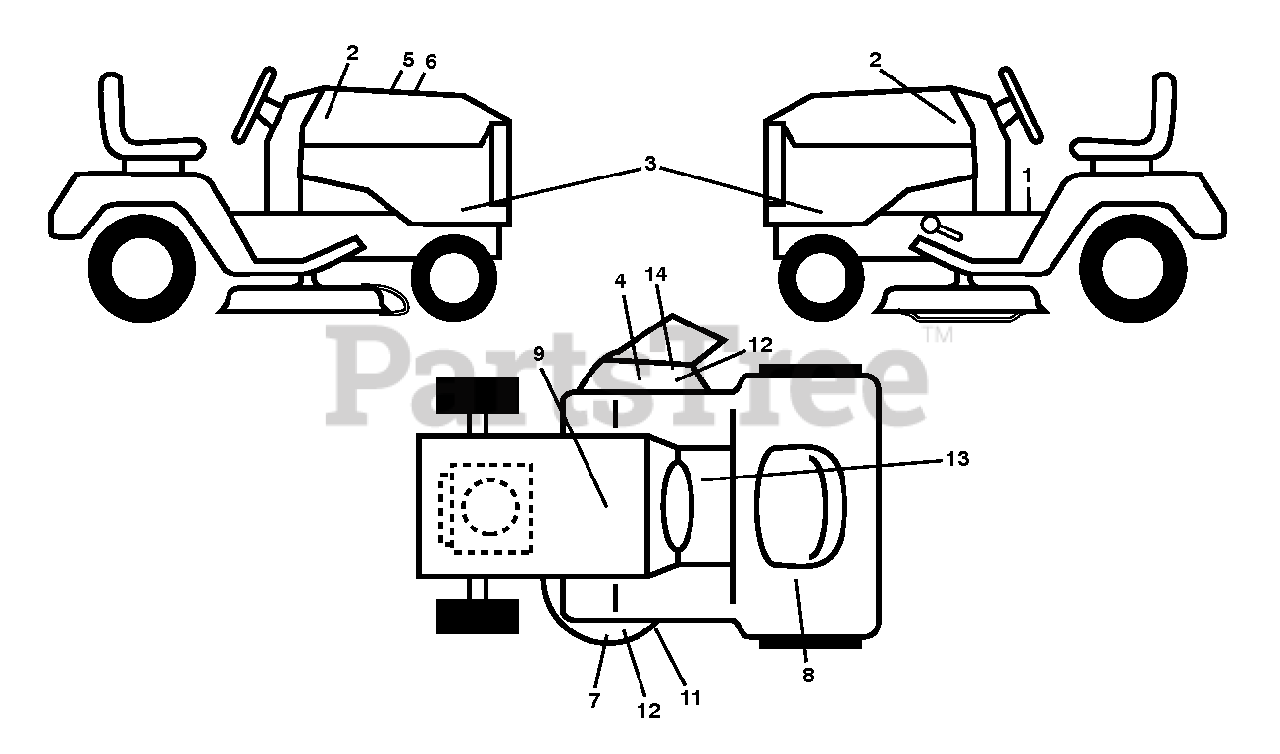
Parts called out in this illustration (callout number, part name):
1	DECAL.WARNING.2007.ENG/FR
2	DECAL.BADGE.170MM.TEXTLOGO.
3	DECAL.SDPL.HUSQGT2.YT.48XLS
4	DECAL.DECK.6MIL./DEF.SHLD.WARN
5	DECAL.WARNING.CUST.RESP.E85.
6	DECAL.RPL.KH.KT7.TLB.48F.K46
7	DECAL DECK DECAL DECAL.POP.LIF
8	DECAL CONTROL DECAL DECAL.RESE
9	DECAL BTRY SYMBOLS
11	DECAL.MOWER.SCH.48/54.PREM
12	DECAL.DECK.6MIL.EURO.NOSTEP
13	DECAL.FWD/REV.PEDAL.SYMBOL
14	DECAL, DECK DEFLECTOR, WARNING
